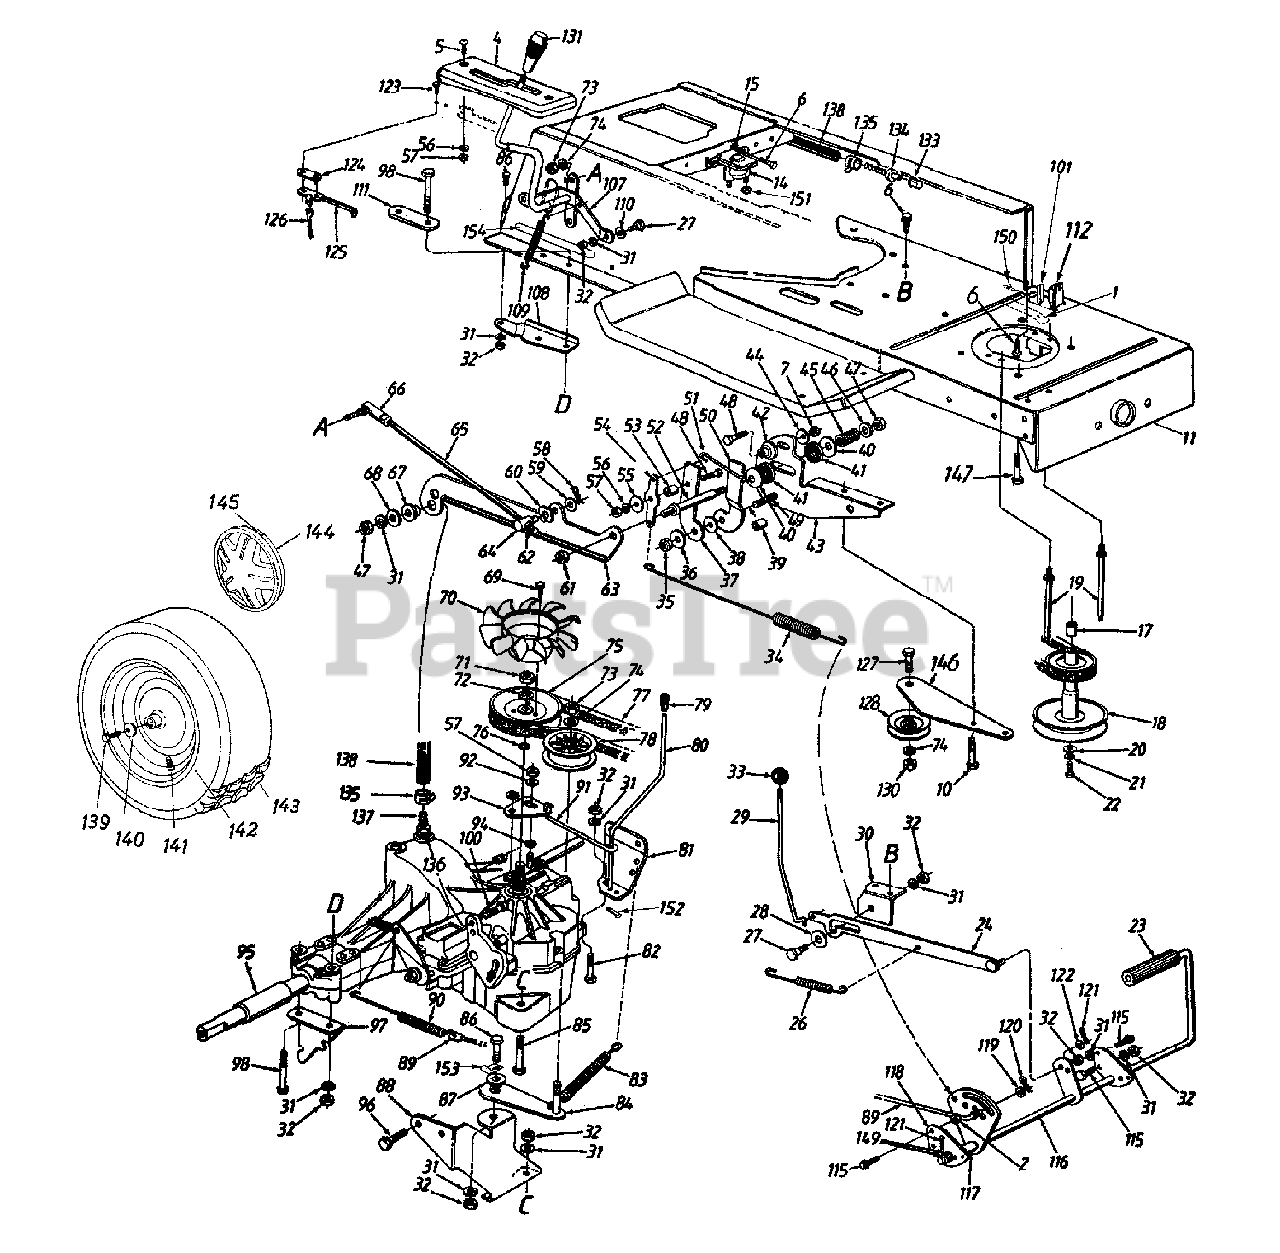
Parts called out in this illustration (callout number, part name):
1	Spring Switch
2	Hex Sems Nut 5/16-18 Thd.
4	Index Bracket
5	Pan Hd. Mach. Scr. 1/4-20 x .75"
6	Hex Wash. Hd. TT-Tap Scr.
7	Hex Nut 1/4-28 Thd.
10	Hex. Bolt 1/4-28 x .62" Lg.
14	Solenoid
15	Ext. L-Wash. 1/4" I.D.
17	Spacer
18	Engine Pulley
19	Belt Guard Stud 4.75" Lg.
20	Fl-Wash. 7/16" I.D. x 1.25" O.D.
21	L-Wash. 7/16" I.D.
22	Hex Bolt 7/16-20 x 1.25" Lg.
23	Foot Pad
27	Shld. Bolt .437" Dia. x .268"
28	Fl-Wash. 7/16" I.D. x 1-3/8" O.D.
29	Lock-up Rod
30	Bracket
31	L-Wash. 5/16" I.D.
32	Hex Nut 5/16-18 Thd.
33	Ball Knob
34	Neutral Return Spring
35	Hex Nut 5/16-24 Thd.
36	Fl-Wash. .344" I.D. x 1" O.D.
37	Scissor-Flat
38	Fl-Wash. .33" I.D. x 1.25" O.D.
39	Spacer
40	Bell-Wash. .4" I.D. x 1.13" O.D.
41	Friction Washer
42	Centering Gauge Spacer
43	Neutral Return Mtg. Brkt.
44	Bell-Wash. .265" I.D. x .75" O.D.
45	Comp. Spring 1.19" Lg.
46	Fl-Wash. .26" I.D. x .72" O.D.
47	Hex Nut 5/16-24 Thd.
48	Hex Bolt 1/4-28 x 1" Lg. (Gr. 5)
49	Rib Neck Bolt 5/16-24 x .84" Lg.
50	Scissor-Offset
51	Neutral Return Rod
52	Friction Disc Stud
53	Shld. Spacer
54	Neutral Return Lever
55	Fl-Wash. .265" I.D. x 1" O.D.
56	L-Wash. 1/4" I.D.
57	Hex Nut 1/4-20 Thd.
58	Hairpin Clip
59	Fl-Wash. .375" I.D. x .87" O.D.
60	Spring Wash. .39" I.D.
61	Hex L-Nut 3/8-24 Thd.
62	Hex Jam Nut 3/8-24 Thd.
63	Neutral Return Brkt.
64	Ferrule 3/8-24 Thd.
65	Control Rod
66	Ball Joint 3/8-24 Thd.
67	Shld. Spacer .5" Dia. x .27" Lg.
68	Fl-Wash. .349" I.D. x .879" O.D.
69	Hex Tap Scr. #12 x .62" Lg.
70	Fan
71	Hex Nut 1/2-20 Thd.
72	L-Wash. 1/2" I.D.
73	Hex Nut 3/8-24 Thd.
74	L-Wash. 3/8" I.D.
75	Transmission Pulley
76	Wire Ring
77	V-Belt
78	Fl-Idler Pulley 2.75" O.D.
79	Rod End Grip
80	Bypass Control Lever
83	Ext. Spring 6.12
86	Hex Bolt 5/16-18 x .75" Lg.
87	Shld. Spacer .5" Dia. x .27" Lg.
90	Ext. Spring
91	Bypass Actuator Rod
92	Fl-Wash. .281" I.D. x .5" O.D.
93	Bypass Adjustment Brkt.
94	External L-Wash. 1/4" I.D.
95	Sleeve .758" I.D. x 1" O.D.
96	Hex. TT-Tap Scr. 5/16-18 x .62"
100	Hex Bolt 5/16-24 x 1" Lg.
101	Hex Wash. Hd. AB-Tap Scr.
107	Speed Control Lever Ass'y.
110	Spr-Wash. .445" I.D. x .75" O.D.
112	Safety Switch (Clutch)
115	Hex TT-Tap Scr. 5/16-18 x 7/8"
120	Cotter Pin 3/32" Dia.
121	Cotter Pin 1/8" Dia.
122	Fl-Wash. .385" I.D. x .62" O.D.
123	Hex AB-Tap Scr. #8 x .5" Lg.
124	Insulator Nut Plate
125	Reverse Safety Switch
126	Extension Wire
127	Hex Bolt 3/8-16 x 1.5" Lg.
128	Idler Pulley
130	Hex Nut 3/8-16 Thd.
131	Shift Knob
133	Vent Cap
134	Plastic Vent
135	Clamp
136	O-Ring
137	Hose Fitting
138	Fuel Line 18" Lg.
139	Hex Bolt 5/16-24 x .75" Lg.
140	Bell-Wash. .345" I.D. x .88" O.D.
141	Air Valve
142	Rim Only
143	Wheel Ass'y. Comp.
144	Hub Cap (Gray)
145	Spring Clip
